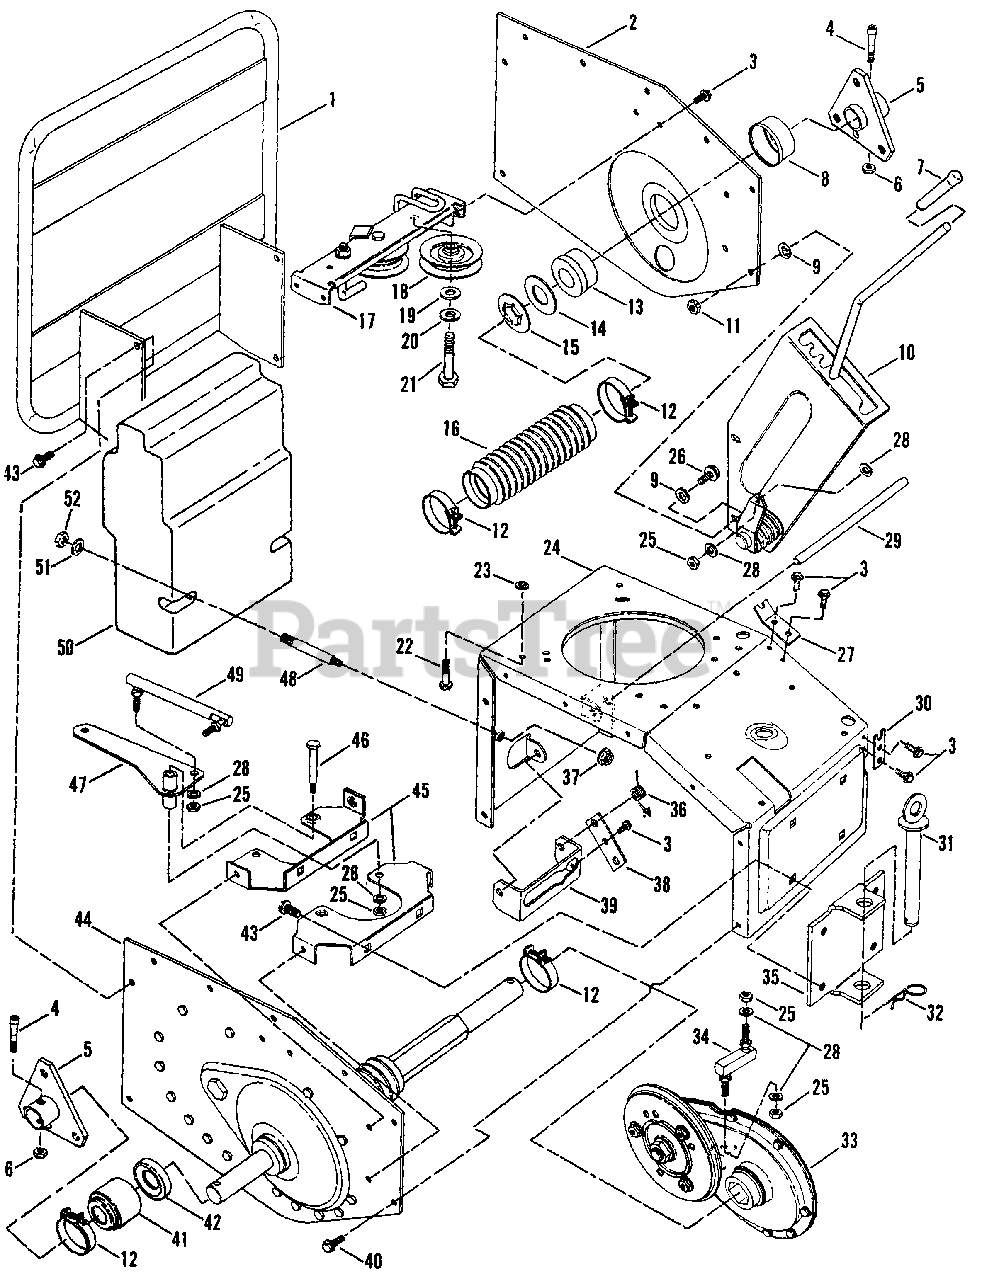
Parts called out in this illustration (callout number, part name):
1	BAR, Stand-Up
2	FRAME, Right Side
3	SCREW, 1/4-20 x 3/8" Self-Tapping
4	BOLT, 5/16-24 x 1 5/8" Tapered
5	HUB, Wheel, 3 Hole 3/4" ID 1.38" Long Tube
6	NUT, 5/16-24 Special Hex Lock
7	GRIP
8	CAP, Seal L.H. 3/4"
9	WASHER, 5/16 Internal/External Tooth Lock
10	ASSEMBLY, Shift Quadrant
11	NUT, 5/16-18 Hex Lock
12	CLAMP, 1-7/8"
13	BEARING, Axle .76" ID x 1.626"/1.75" OD x 1.75" Long
14	WASHER, Thrust (Nylon)
15	WASHER, Thrust
16	SEAL, Long
17	ASSEMBLY, Idler Bracket
18	PULLEY, V-Idler 2.62" OD
19	WASHER, 3/8" Flat
20	WASHER, 3/8 Split Lock
21	SCREW, 3/8-16 x 1 1/2" Hex Head Cap
22	BOLT, 5/16-18 x 1 1/2" Hex Head Cap (Engine Mounting)
23	RETAINER, Bolt 5/16"
24	FRAME
25	NUT, 5/16-24 Hex
26	SCREW, 5/16-18 x 1" Self-Tapping
27	(NLA) CLIP, Cable
28	WASHER, 5/16 Split Lock
29	(NLA) ROD
30	(NLA) CLIP, Control
31	CLEVIS PIN, 3/4 X 6-1/16, ZP (Hitch)
32	HAIR PIN, 2.25, .093 ZP
33	ASSEMBLY, Primary Chain Case
34	LINK, Short Shift 1"
35	CLEVIS
36	(NLA) SPRING
37	NUT, 5/16-18 Hex Flange Lock
38	(NLA) LEVER
39	YOKE, Clutch
40	SCREW, 5/16-18 x 1/2" Self-Tapping
41	BOOT
42	SEAL, OIL .750" ID x 1.832" OD
43	SCREW, 3/8-16 x 1" Self-Tapping
44	(NLA) ASSEMBLY, Left Frame Drive (RT8 & 5X)
45	BRACE
46	BOLT, 5/16-24 x 3" Shoulder
47	BELLCRANK, Shift
48	STUD, Weight
49	LINK, Shift 4.5"
50	(NLA) WEIGHT
51	WASHER, 7/16 Flat
52	NUT, 7/16-14 Hex Lock
